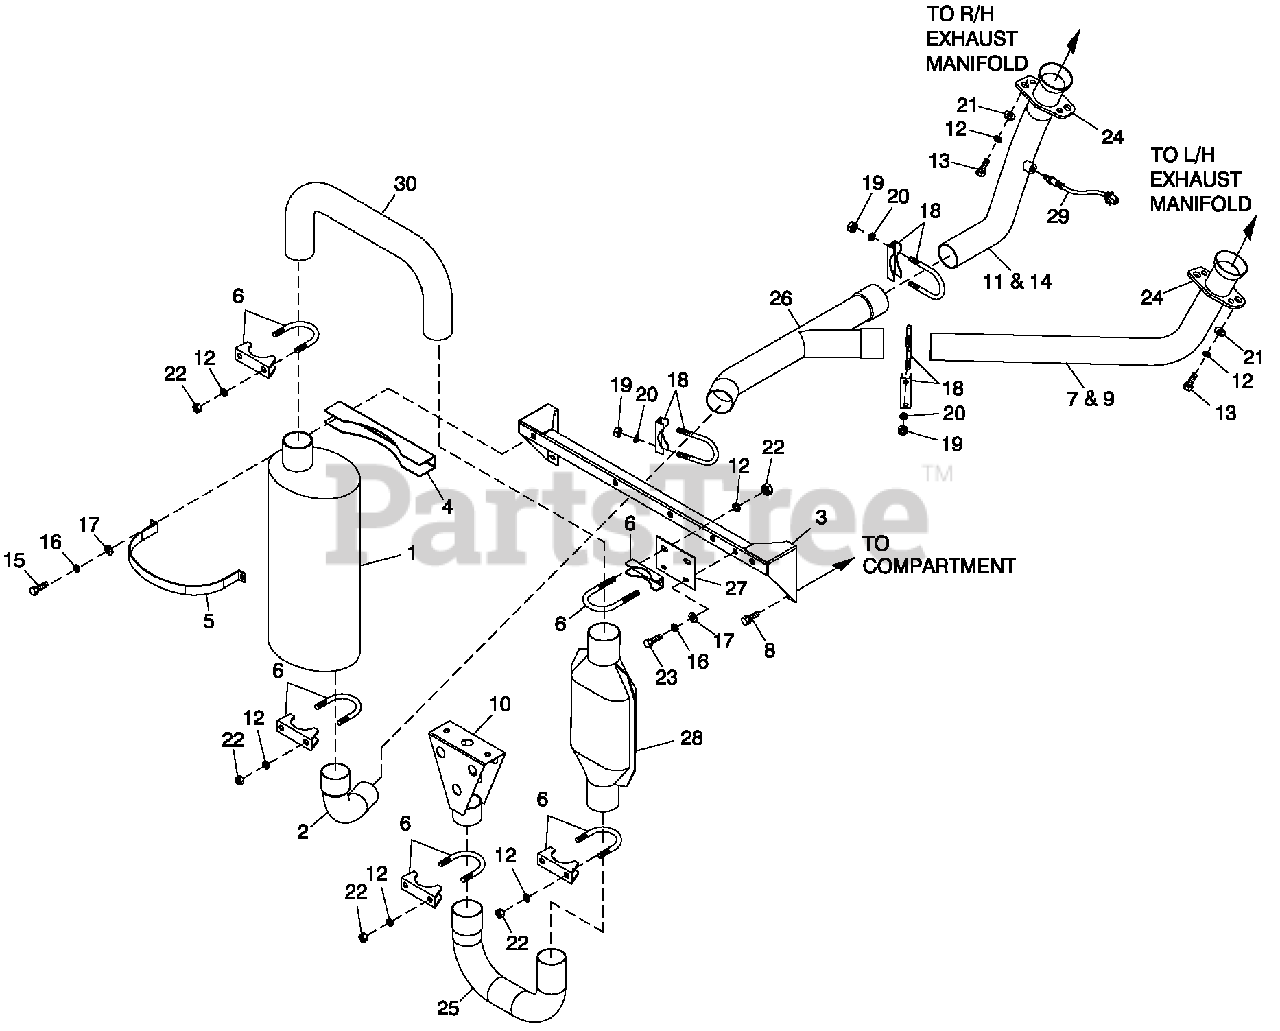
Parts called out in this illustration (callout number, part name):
1	MFLR 7"X9"X18-1/2"2-1/2"IN/OUT
2	EXHAUST ELBOW 2"ID X 2-1/2"OD
3	BRAC KET MUFFLER
4	MUFFLER BRACKET STIFFENER
5	MUFFLER STRAP
6	BOLT U 3/8-16X2.62
7	PIPE EXHAUST LEFT 2"OD G3 4.2L
8	SCREW THF M6-1 X 16 N WA Z/JS
10	DIFFUSER EXHAUST WELDMENT
11	PIPE EXHAUST RIGHT G3 4.2 EMSN
12	WASHER LOCK 3/8 SS
13	SCREW HHC M10-1.5 X 45 SS FTH
15	SCREW HHC M6-1.0 X 35 G8.8 BLK
16	WASHER LOCK M6-1/4
17	WASHER FLAT 1/4-M6 ZINC
18	BOLT U 5/16-18X2.25
19	NUT HEX 5/16-18 STEEL
20	WASHER LOCK M8 SS
21	WASHER FLAT 3/8 SS
22	NUT HEX 3/8-16 STEEL
23	SCREW HHC M6-1.0X 16 G8.8
24	EXHAUST FLANGE 2" PIPE
25	PIPE, EXHAUST MUFFLER OUT
26	Y-PIPE EXHAUST 2"OD 4.2L G3
27	PLATE, CATALYST MOUNTING
28	CATALYST AF-RATIO
29	SENSOR OXYGEN
30	PIPE, EXHAUST CROSSOVER EMSSM
